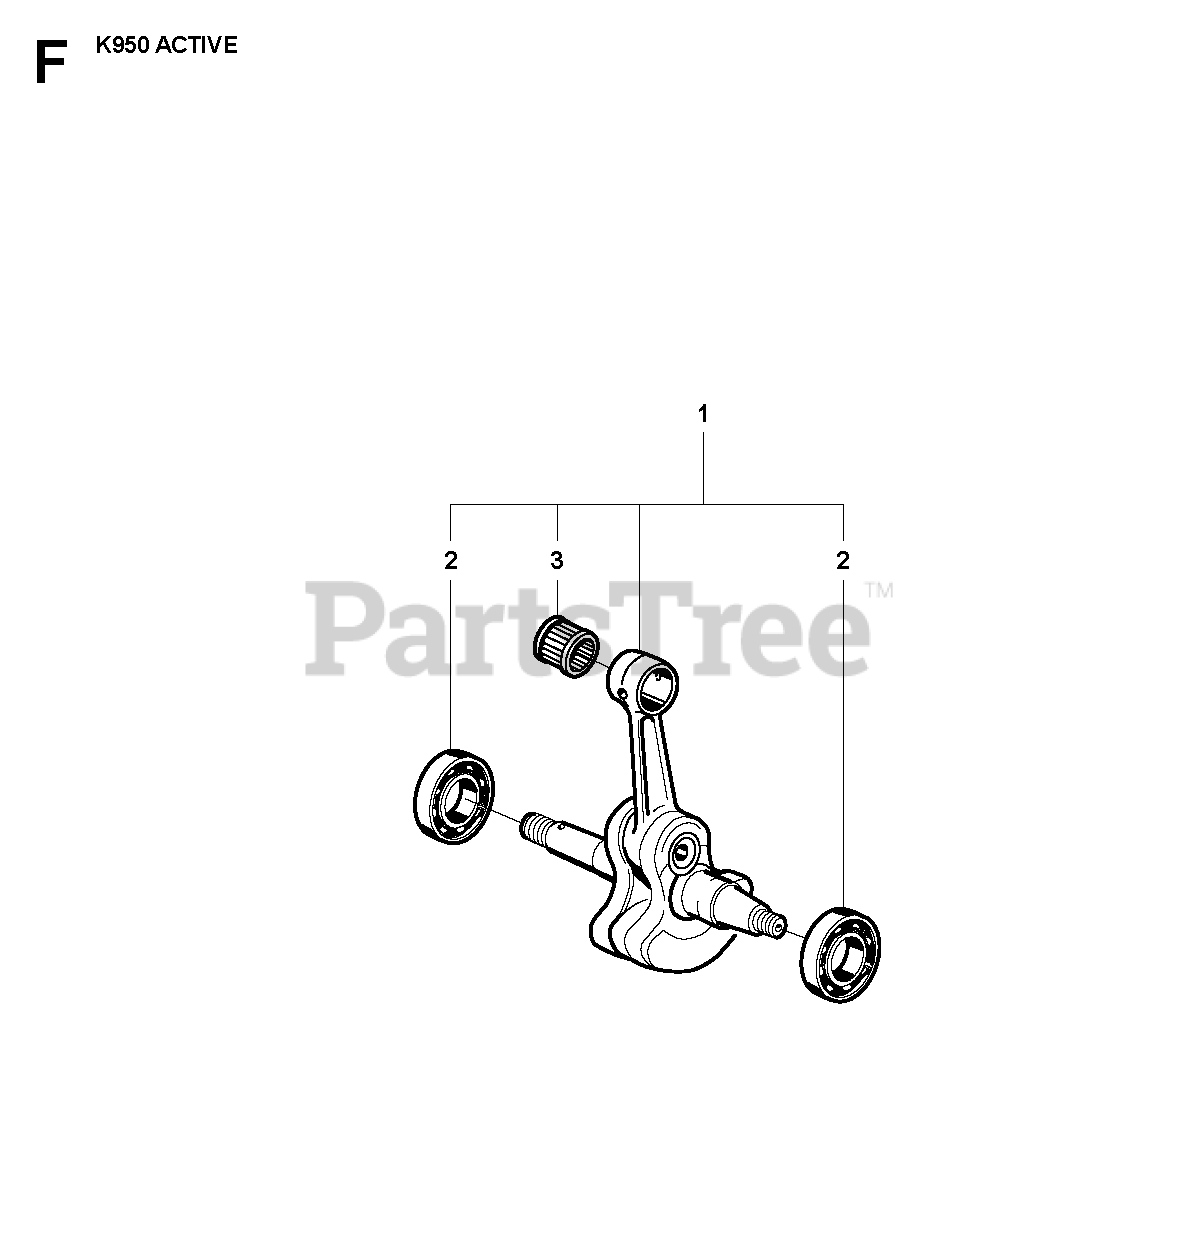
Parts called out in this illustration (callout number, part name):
1	CRANKSHAFT ASSYIncl. 2, 3
2	BALL BEARING
3	NEEDLE BEARING
